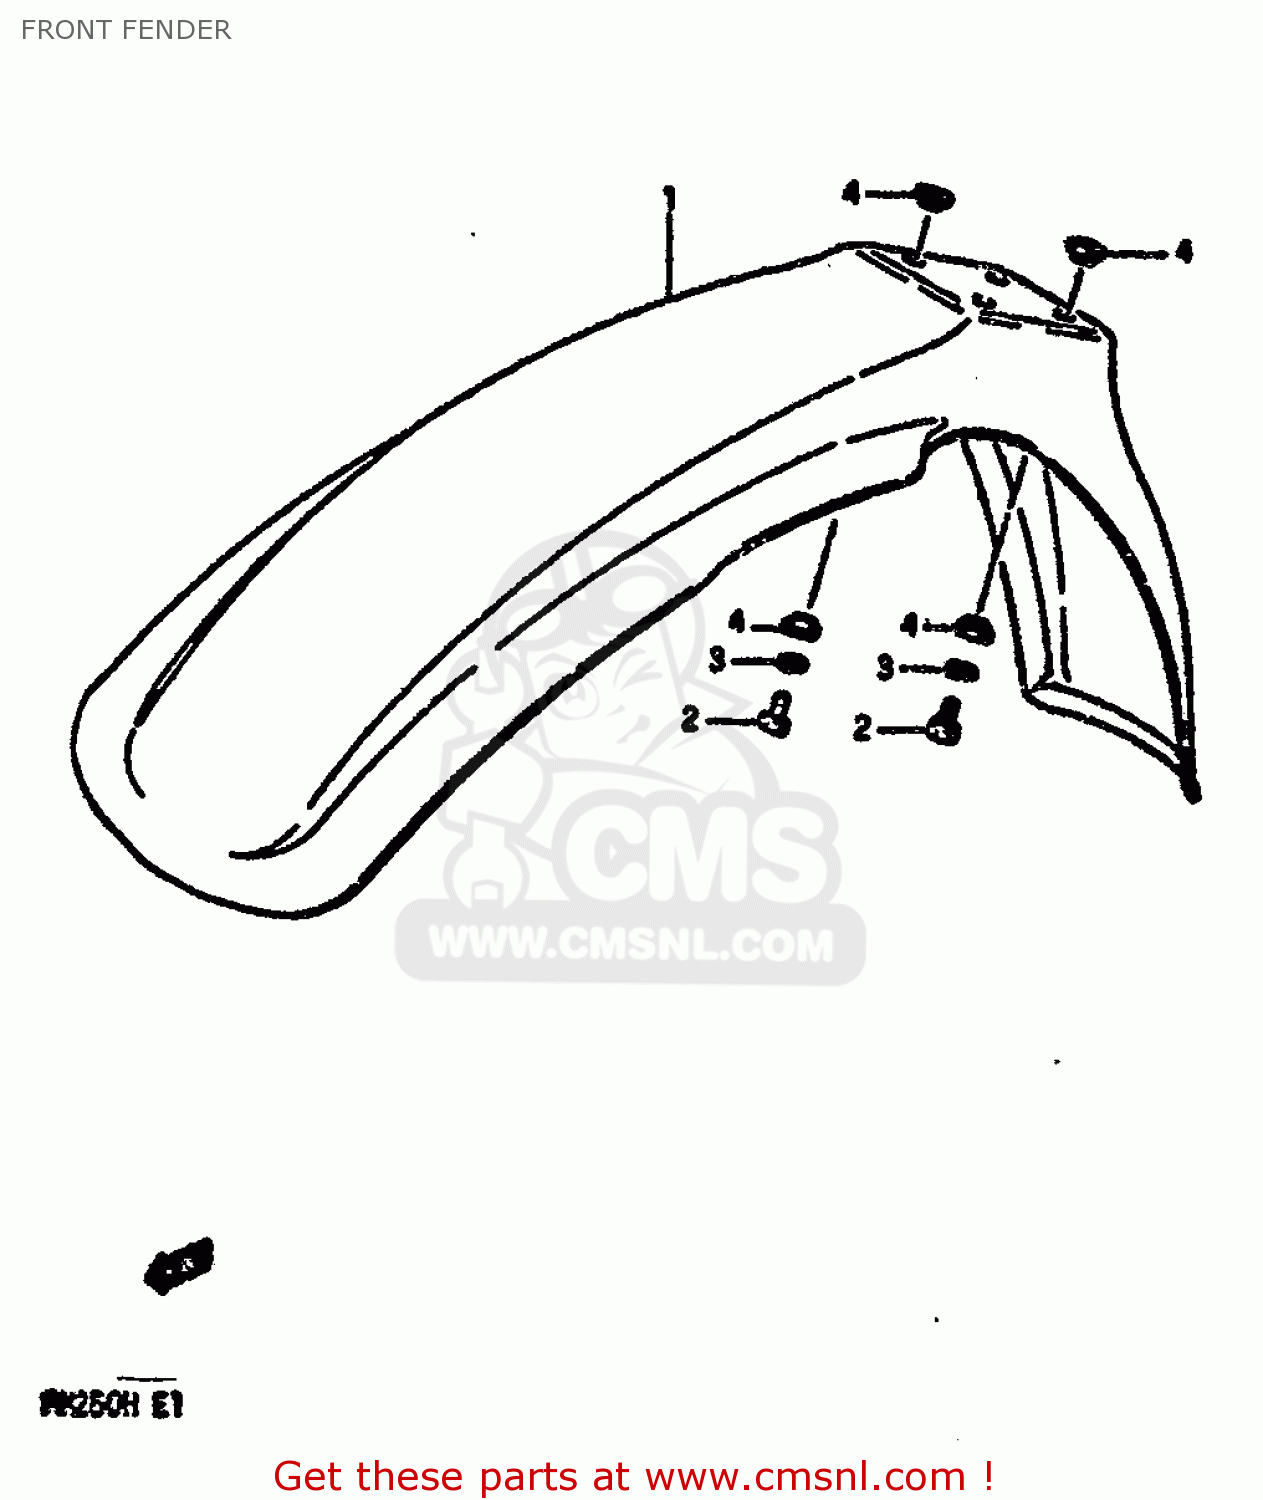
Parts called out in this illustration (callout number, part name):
1	FENDER,FR
2	BOLT
3	WASHER,LOCK
4	WASHER
